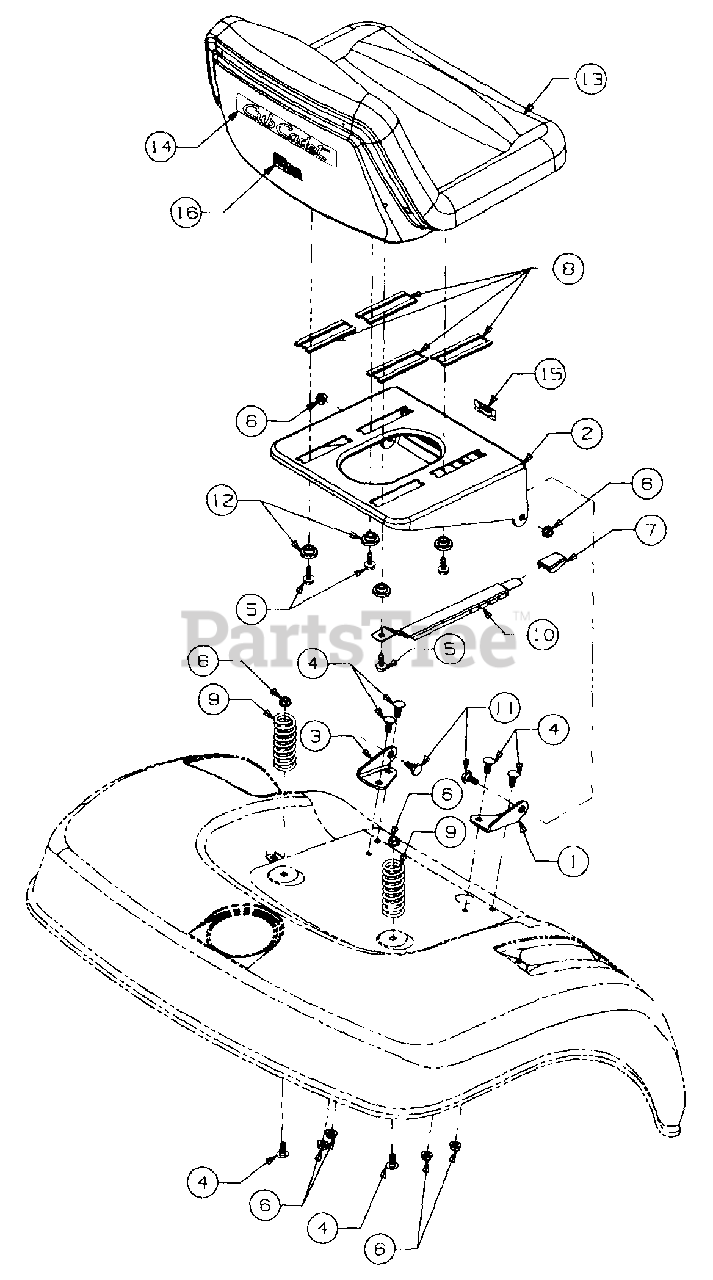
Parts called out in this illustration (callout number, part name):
1	Bracket, RH Seat Pivot
2	Seat, Base
3	Bracket, LH Seat Pivot
4	Bolt, Carriage, 5/16-18 x .75
5	Screw, Hex Wash Hd Tapp 5/16-18 x .75
6	Nut, Hex Flange Lock, 5/16-18
7	Knob, Seat Adjuster
8	Slide, Seat
9	Spring, Compression 1.9 OD x 24 Lg
10	Adjuster, Seat
11	Bolt, Shoulder
12	Spacer, Shoulder
13	Seat, Medium Back
14	Graphic, Seat Back Script
15	Graphic, Seat Adjuster
16	Graphic, Made in USA
